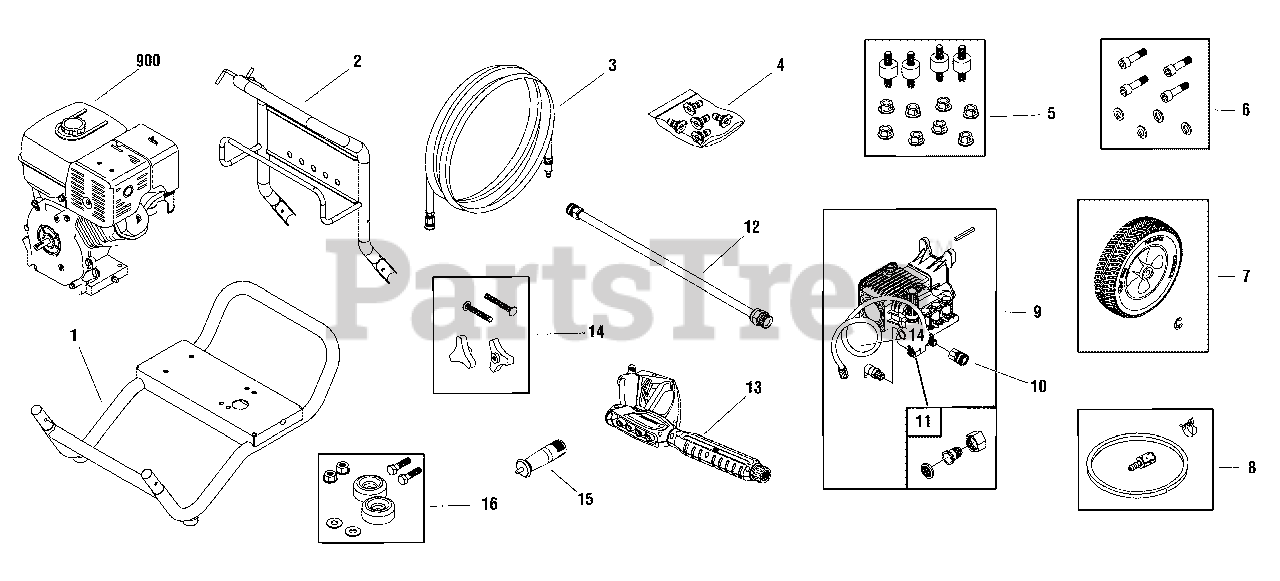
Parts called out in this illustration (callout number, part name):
4	KIT, QC Nozzles
5	KIT, Hardware Engine Mounting
6	KIT, Hardware Pump Mounting
9	PUMP
10	FITTING
11	ADAPTER, Garden Hose
12	EXTENSION, QC
14	KIT, Hardware Handle
16	MOUNT, Vibration
900	* ENGINE
